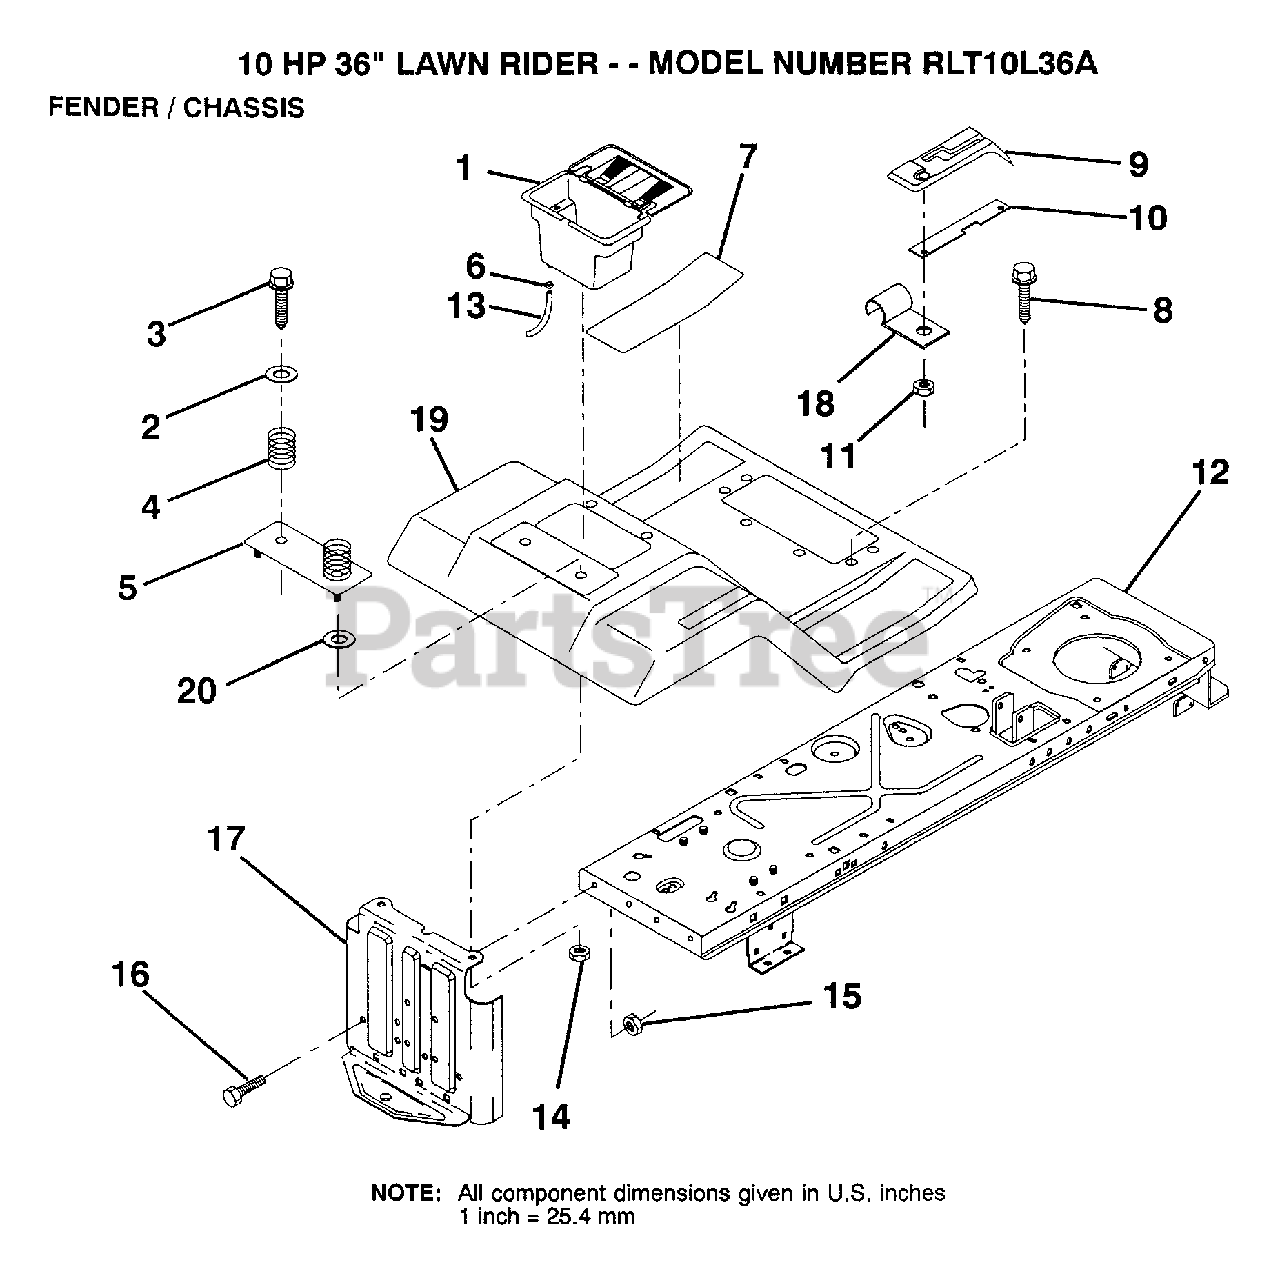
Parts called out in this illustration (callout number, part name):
2	WASHER
3	SCREW
4	SPRING COMPRESSIO
5	"PLATE, BATTERY"
6	HOSE CLAMP T
7	PAD FOOTREST
8	SCREW
9	CONSOLE SHFT 4SP
11	NUT
14	NUT
16	BOLT
17	DRAWBAR
18	"CLIP,INSULATOR"
